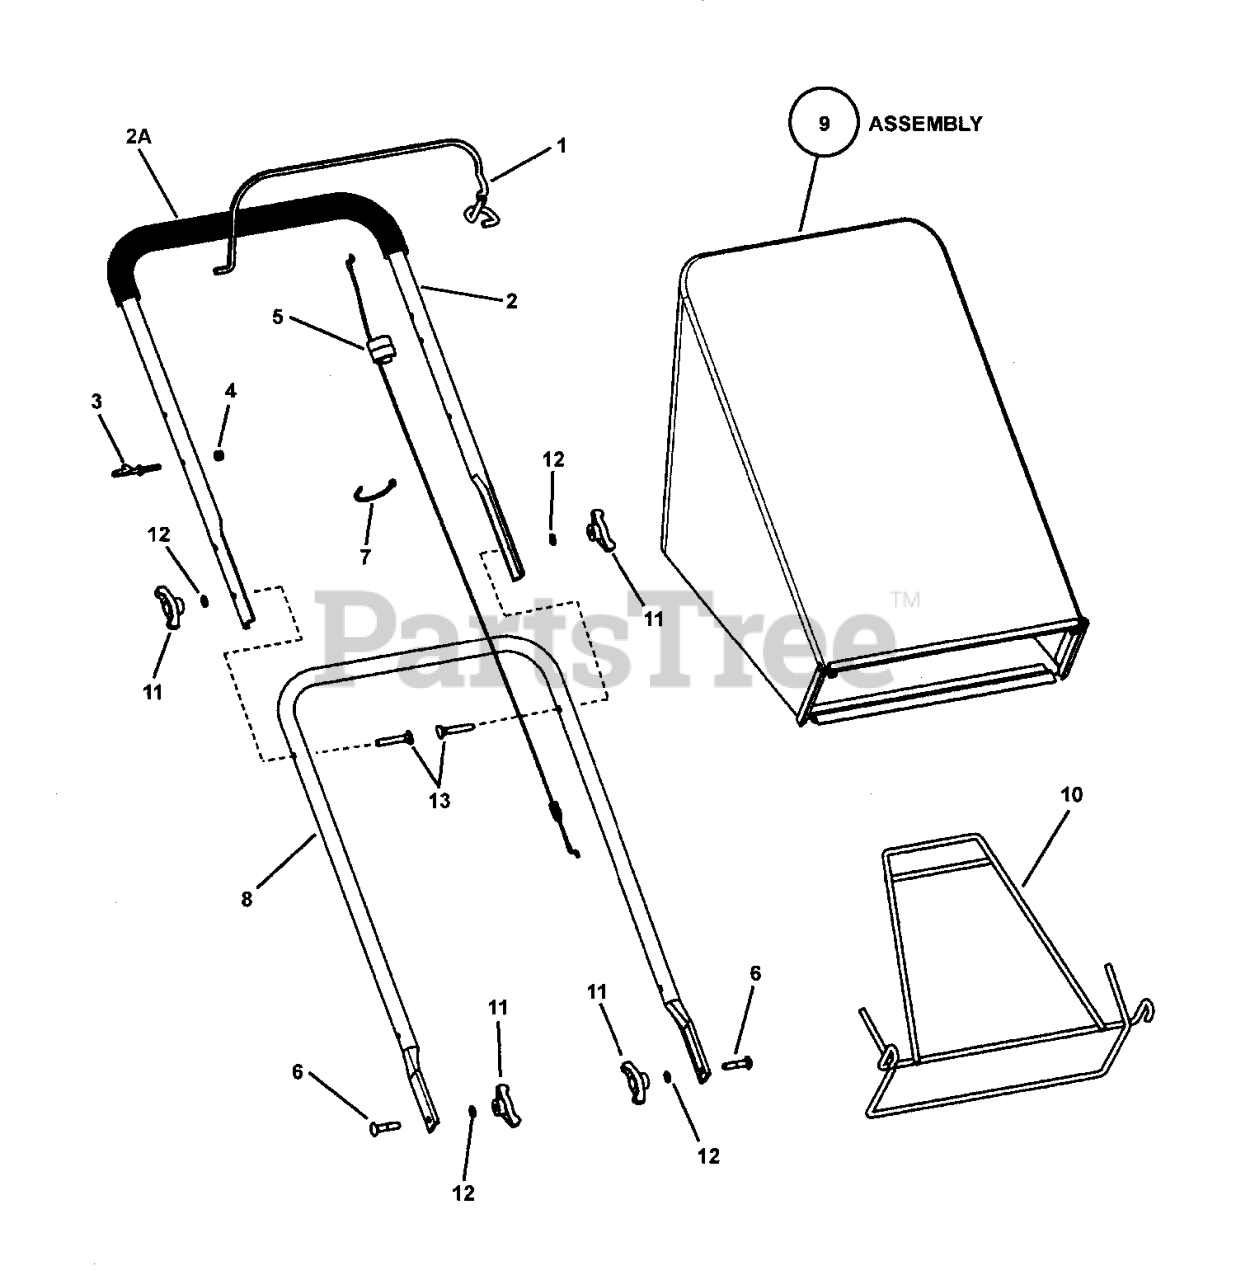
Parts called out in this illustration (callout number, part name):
1	BAIL, OPC Push
2	HANDLE, Upper
2A	FOAM GRIP, 18.75"
3	GUIDE, Rope (1/4-20 thread)
4	NUT, 1/4-20 Nyloc
5	CABLE, Bail (45.00" overall length)
5	CABLE, Bail (41.50" overall length)
6	BOLT, 5/16-18 x 1-1/2" Short Square Neck Carriage, GR 5 YZ
7	WIRE TIE, 11 Inch Std Black Nylon
8	HANDLE, Lower
9	ASSY, Grass Bag, Cloth- includes next item below
10	WELDMENT, Grass Bag Frame
11	KNOB, Wing, 5/16-18
12	WASHER, 5/16" Internal Tooth Lock
13	BOLT, 5/16-18 x 2" Curved Head Square Neck, GR 2
